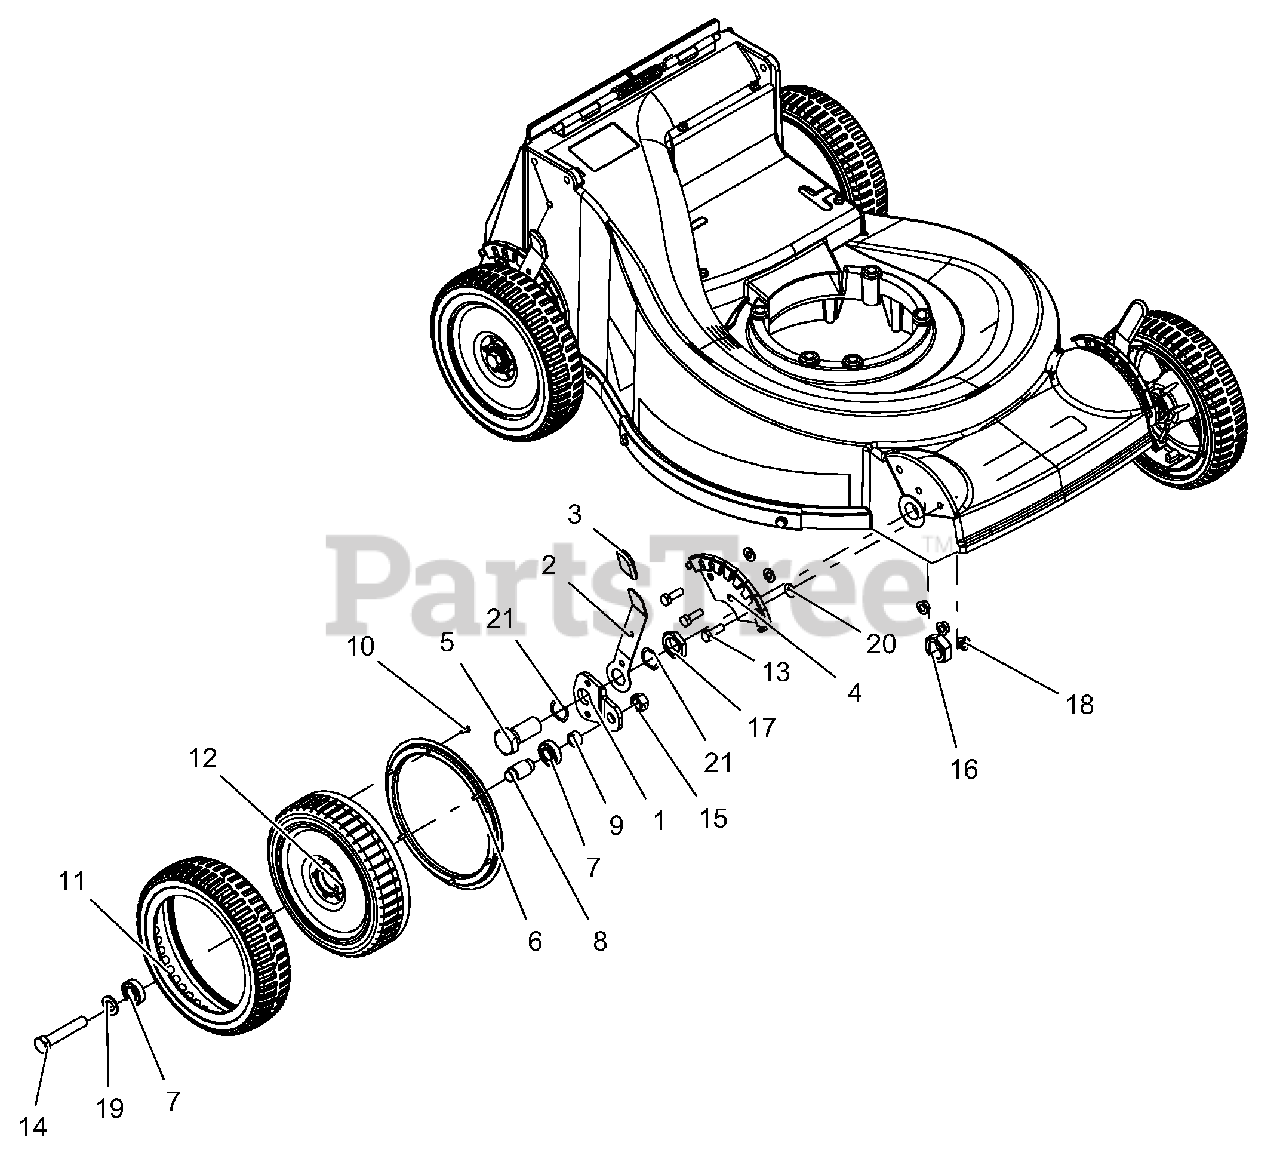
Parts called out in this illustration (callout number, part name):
1	BRKT, WHEEL
2	LEVER, HEIGHT ADJUST
3	GRIP, HEIGHT ADJUST
4	LOCATOR, HEIGHT CONTROL
5	HUB, FRONT AXLE
6	RING, TIRE RETAINING
7	BRG, WHEEL
8	BSHG, WHEEL
9	BSHG, SPCR
10	SCR, MACHINE-#8-32 X .375 PANHD
11	TIRE, MOWER
12	WHEEL, ALUMINUM
13	BLT-HEX .31-18X1.00 GR5 YWZC
14	BLT-HEX .50-13X2.75 GR5 YWZC
15	NUT-LK-CTR .50-13 YWZC
16	NUT-JAM .875-14
17	NUT-JAM .875-14 THIN
18	NUT, LK-TOP-FLG .312-18 YWZC
19	WSHR-FL-STL M12 13X25X2 YWZC
20	WSHR-FL-STL.344X.688X.065YWZC
21	WASHER, WAVE
